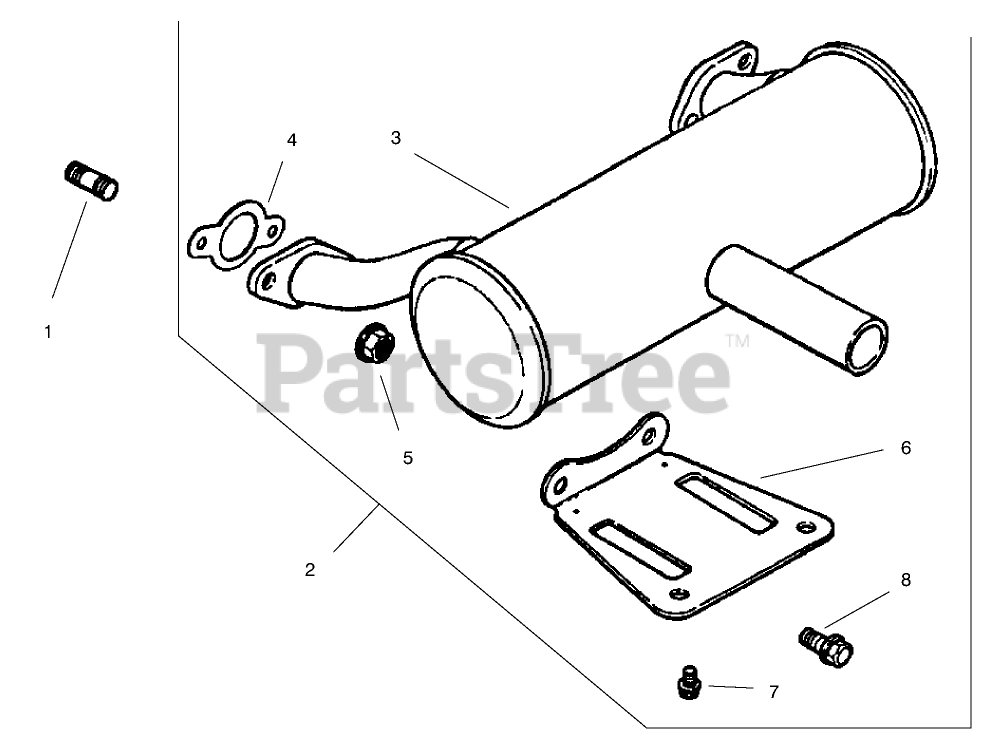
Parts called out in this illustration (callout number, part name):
1	Stud
2	Kit, low mount muffler (Includes 3-8)
3	Muffler
4	Gaskt-Exhaust
5	Nut
6	Bracket-Muffler
7	Screw
8	Screw, tank bracket - starter end
